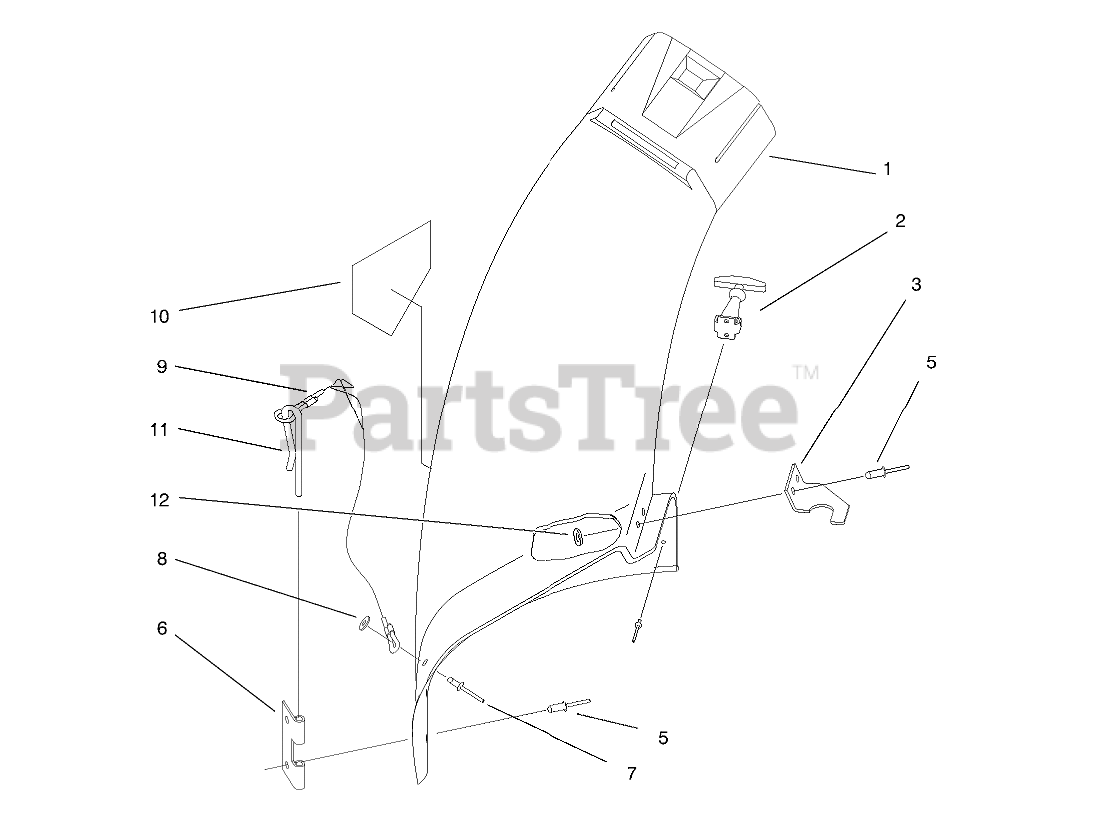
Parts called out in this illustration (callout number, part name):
1	ELBOW-BAGGER, 38 INCH
2	Latch-38"
3	LATCH-ELBOW, BAGGER
4	RIVET-POP
5	RIVET-BLIND
6	BRACKET-MOUNTING, CHUTE
7	RIVET-BLIND
8	WASHER-PLAIN
9	LANYARD
10	DECAL-DANGER
11	PIN-LOCKING, CHUTE
12	WASHER-FLAT
